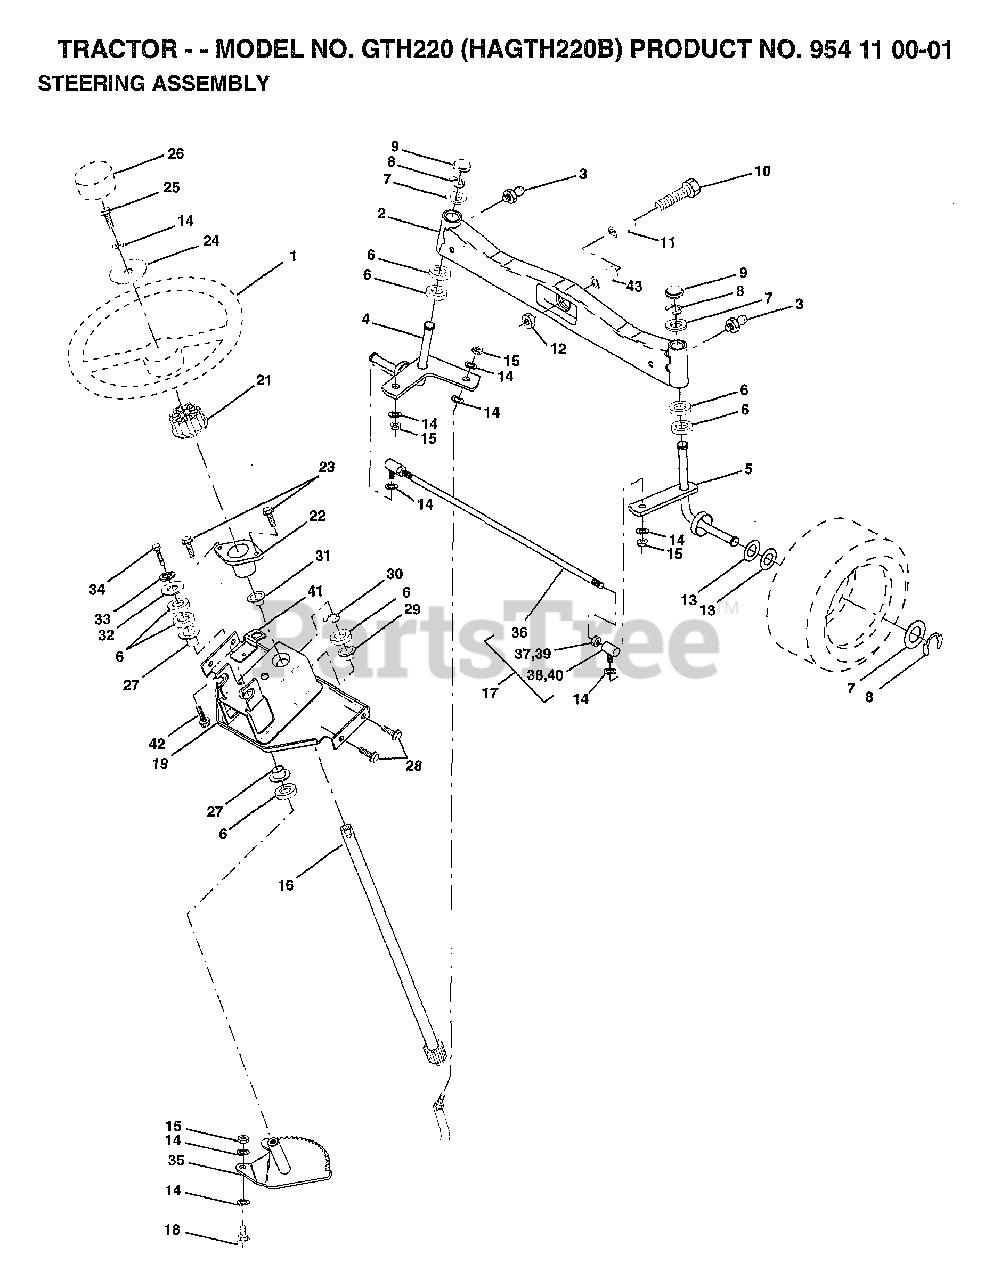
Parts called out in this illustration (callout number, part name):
1	STEERING WHEEL
2	AXLE.FRT.CAST.MAC
8	RING KLIP #T5304-75
10	BOLT FIN HEX 5/8-11 X 2-3/4
12	NUT LOCK FLANGE 5/8-11
14	WASHER LOCK HVY HLCL SPR 3/8
24	WASHER 13/32 X 2-3/8 X 8 GA
25	BOLT FIN HEX 3/8-16 X 1
26	"INSERT,STR WHEEL"
28	SCREW THDROL 3/8-16X3/4 TY-TT
30	RING, KLIP TRUARC #5304-75
32	WASHER, 11/32 X 1 X 10 GA.
33	WASHER, LOCK
34	BOLT, HEX 5/16-18 X 3/4
37	JAM NUT RH THREAD
39	JAM NUT LH THREAD
42	SCREW, 5/16-18 X 1/2 HEX, SELF TAPPING
